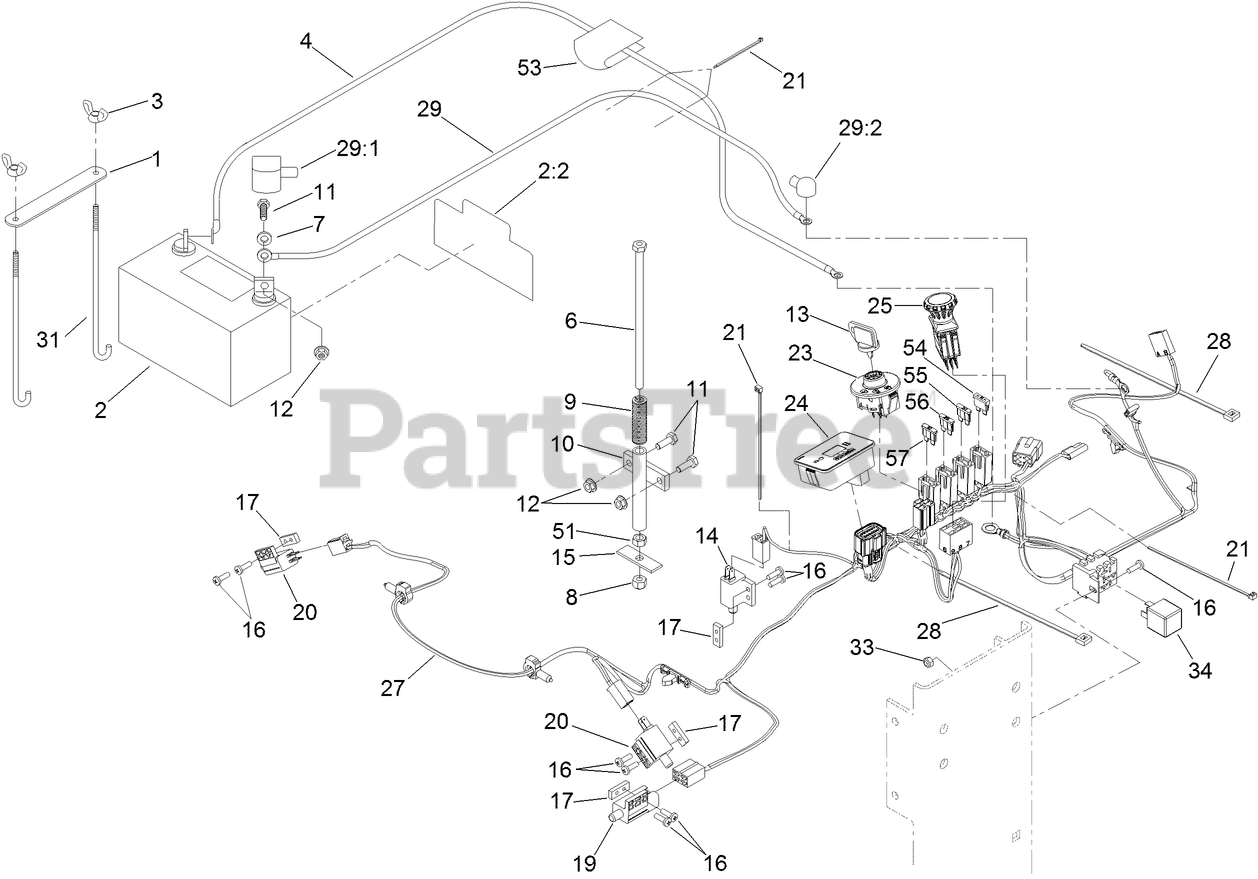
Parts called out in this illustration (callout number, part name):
1	STRAP-HOLDDOWN, BATTERY
2	BATTERY
2:2	Decal-Battery
3	WINGNUT
4	WIRE-GROUND
6	SCREW-HH
7	WASHER-FLAT
8	NUT-LOCK, NI
9	SPRING-SWITCH, SEAT
10	MOUNT-SPRING, SEAT
11	SCREW-HH
12	NUT-HF
13	KEY-IGNITION
14	SWITCH-CLOSED, NORMALLY
15	PLATE-SWITCH, SEAT
16	SCREW-PPH
17	PLATE-TAPPED
19	SWITCH
20	SWITCH-OPEN, NORMALLY
21	TIE-CABLE
23	SWITCH-IGNITION
24	HOUR METER ASM
25	SWITCH-PTO, 10 AMP
27	HARNESS-ELECTRICAL
28	TIE-PLASTIC
29	POSITIVE BATTERY CABLE ASM
29:1	INSULATOR-BATTERY
29:2	INSULATOR-SOLENOID
31	BOLT-HOLDDOWN
33	NUT-LOCK, NI
51	NUT-HEX
53	DECAL-INSTRUCTIONS, CHARGING
54	FUSE-BLADE, 15 AMP
55	FUSE-BLADE, 30 AMP
56	FUSE-BLADE, 25 AMP
57	FUSE-BLADE, 10 AMP
